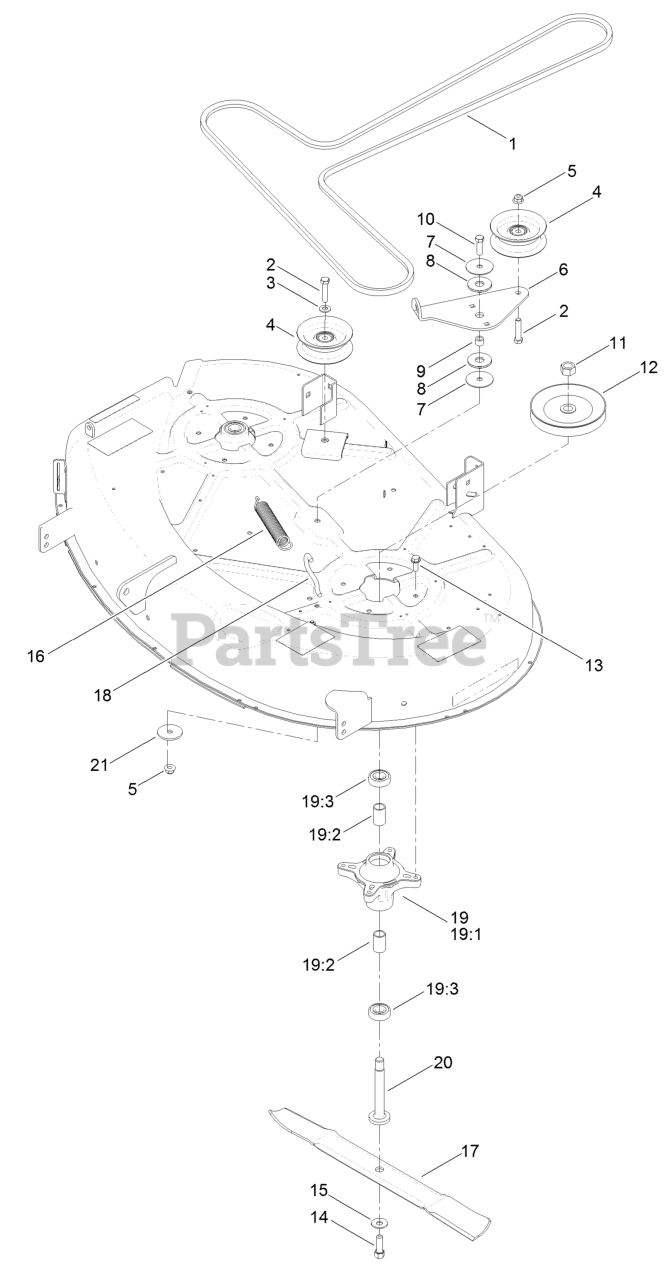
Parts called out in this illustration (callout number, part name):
1	V-BELT
2	SCREW-HH
3	WASHER-FLAT
5	NUT-HF, NI
6	ARM-IDLER
8	WASHER-FRICTION, COMPOSIT
10	SCREW-HH
11	NUT-HEX
12	PULLEY
13	SCREW-TAPTITE
14	SCREW-HH
15	WASHER-BELLEVILLE
16	SPRING-EXTENSION
17	BLADE-HIGH LIFT
18	HOOK-RETURN, SPRING
19	SPINDLE ASM
19:3	BEARING-BALL
20	SHAFT-SPINDLE
21	WASHER-REBOUND
